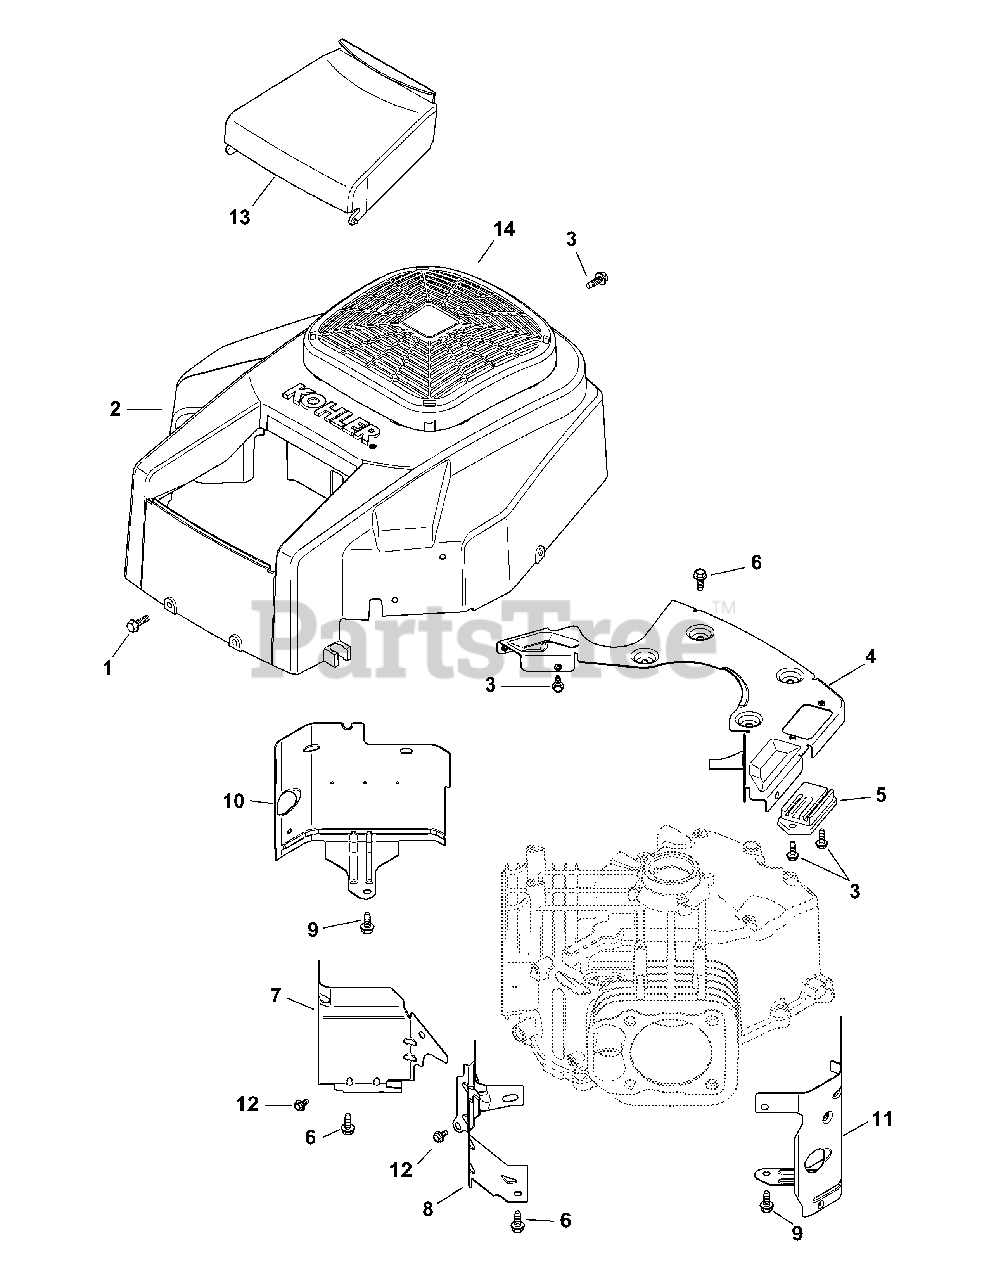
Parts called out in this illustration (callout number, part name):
1	Screw, M6 x 1.7 x 18
2	Blower Housing Kit
3	Flange Screw, M5 x .8 x 16
4	Backing Plate Kit
5	Regulator/Rectifier
6	Flange Screw, M6 x 1.0 x 16
7	Valley Baffle, #1 Cylinder
8	Valley Baffle, #2 Cylinder
9	Flange Screw, M6 x 1.0 x 10
10	Cylinder Barrel Baffle, #1 Side
11	Cylinder Barrel Baffle, #2 Side
12	Flange Screw, M5 x .8 x 10
13	Air Cleaner Cover
